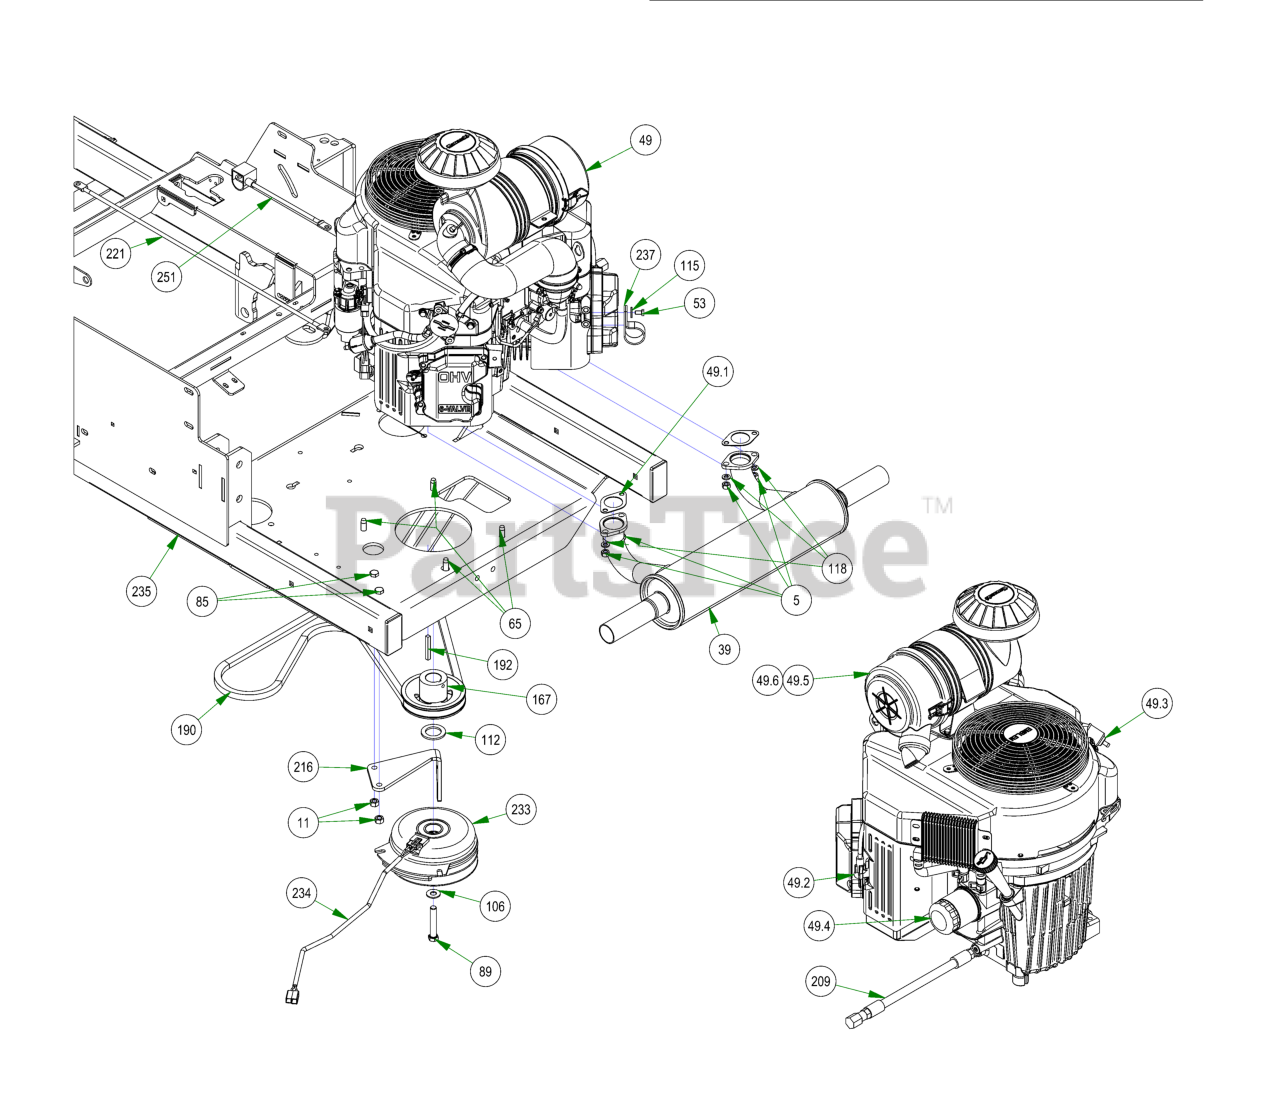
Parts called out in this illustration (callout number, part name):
5	M8-1.25 DIN 934 HEX NUT (CL.8) ZINC
11	3/8-16 HEX NUT ZINC
32	1 1/2 x 3 Frame Plug
39	2019 Rebel/Rogue Kawasaki 1000 Muffler
49	Kawasaki FX1000 Engine
49.1	Exhaust Gasket
49.2	Spark Plug - Kawasaki
49.3	Universal Inline Fuel Filter
49.4	Oil Filter
49.5	Canister Air Filter- Outer
49.6	Canister Air Filter- Inner
53	M6-1.0 X 12MM DIN 933 HEX TAP BOLT (CL 8.8) ZINC
65	3/8-16 X 1-1/8HEX WASHER UNSLOT SERRATED
85	3/8-16 X 1-1/4 HEX CAP SCREW (GR.5) ZINC
89	7/16-20 X 2-1/2 HEX Bolt GR 8 W/ Patch
106	3/8 FLAT WASHER USS (1" OD) ZINC
112	1.140 ID X 1.750 OD X .132 THICK FLAT WASHER PLAIN
115	1/4 USS FLAT WASHER (3/4 OD) ZINC
118	5/16 SPLIT LOCKWASHER ZINC
167	4 3/4 Motor Pulley
190	2019 Rogue Pump Belt 68"
192	1/4 X 2 SQ MACHINERY KEY 1018 STL PLAIN
209	Kawasaki Oil Drain
216	PTO Engager Holder
221	24" Red Battery Cable
233	Clutch Assembly
234	Clutch Pigtail
235	2023 Rogue Frame - Painted
237	Diesel Hydraulic Hose Clamp
251	Starter Cable
253	2019 Harness Adaptor-Gen2 FX-ALL
